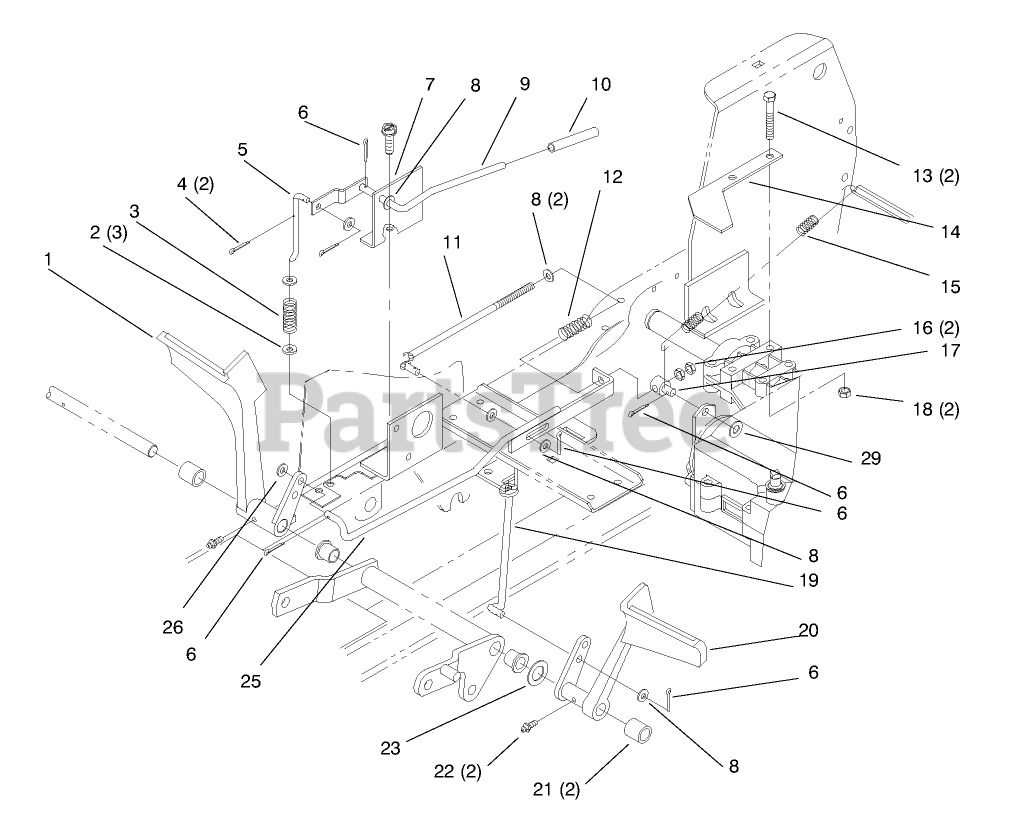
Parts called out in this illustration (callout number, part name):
2	WASHER-FLAT
4	PIN-COTTER
5	ROD - PARKING BRAKE
6	PIN-COTTER
8	WASHER-PLAIN
9	PARK BRAKE LVR WA*B
10	GRIP - PARKING BRAKE
11	ROD - SPRING
12	SPRING - COMPRESSION
13	SCREW-HH
15	SPRING - EXTENSION
16	NUT-JAM
17	TRUNION
18	NUT-LOCK, NI
19	CLUTCH ROD WA
20	PEDAL-CLUTCH
22	FITTING-GREASE
23	WASHER-WAVE
25	ARM-BRAKE
26	WASHER-FLAT
29	WASHER-FLAT
